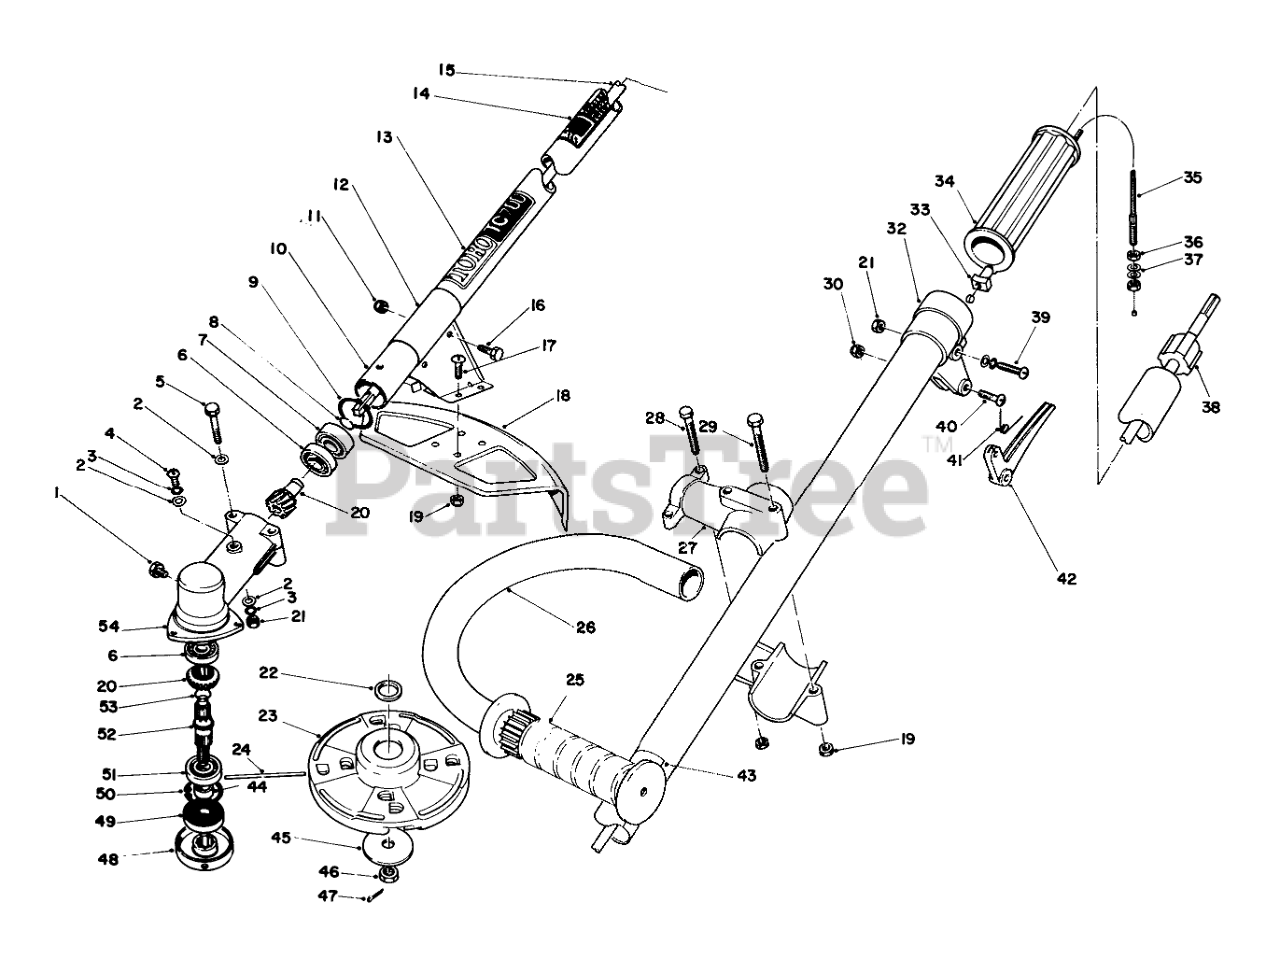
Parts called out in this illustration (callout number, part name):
2	WASHER
3	Washer
4	Screw
6	Ball Bearing
7	Ball Bearing
8	Circlip
9	Circlip
10	Housing Assembly
11	NUT-LOCK, NI
12	Bracket-Shield
13	Decal-TC700
14	Decal
15	Shaft Drive
16	SCREW-HH
17	SCREW-PPH
18	Shield
19	NUT-LOCK, NI
20	Gear Set
21	Nut
22	SPACER
23	Cutter Head (Incl. Ref. #22)
24	LINE PACK (100)
25	LH GRIP
26	Tube-Handle
27	Clamp-"J" Handle
28	10-24X1-1/8 RND HD MS
29	10-24X1-3/4 RND HD MS
32	Bracket, Trigger
33	SPACER
34	GRIP - WILLMAR
35	Throttle Cable
37	Washer
38	Bushing
39	SCREW
40	Screw
41	Spring Return
42	Throttle Trigger
43	Decal Warning
44	Spacer
45	WASHER
47	1/16 X 1 LG COTTER PIN
48	Plate-Blade Fixing
49	Oil Seal
50	Circlip
51	Ball Bearing
52	Shaft P.T.O.
53	Circlip
54	Gear Housing
